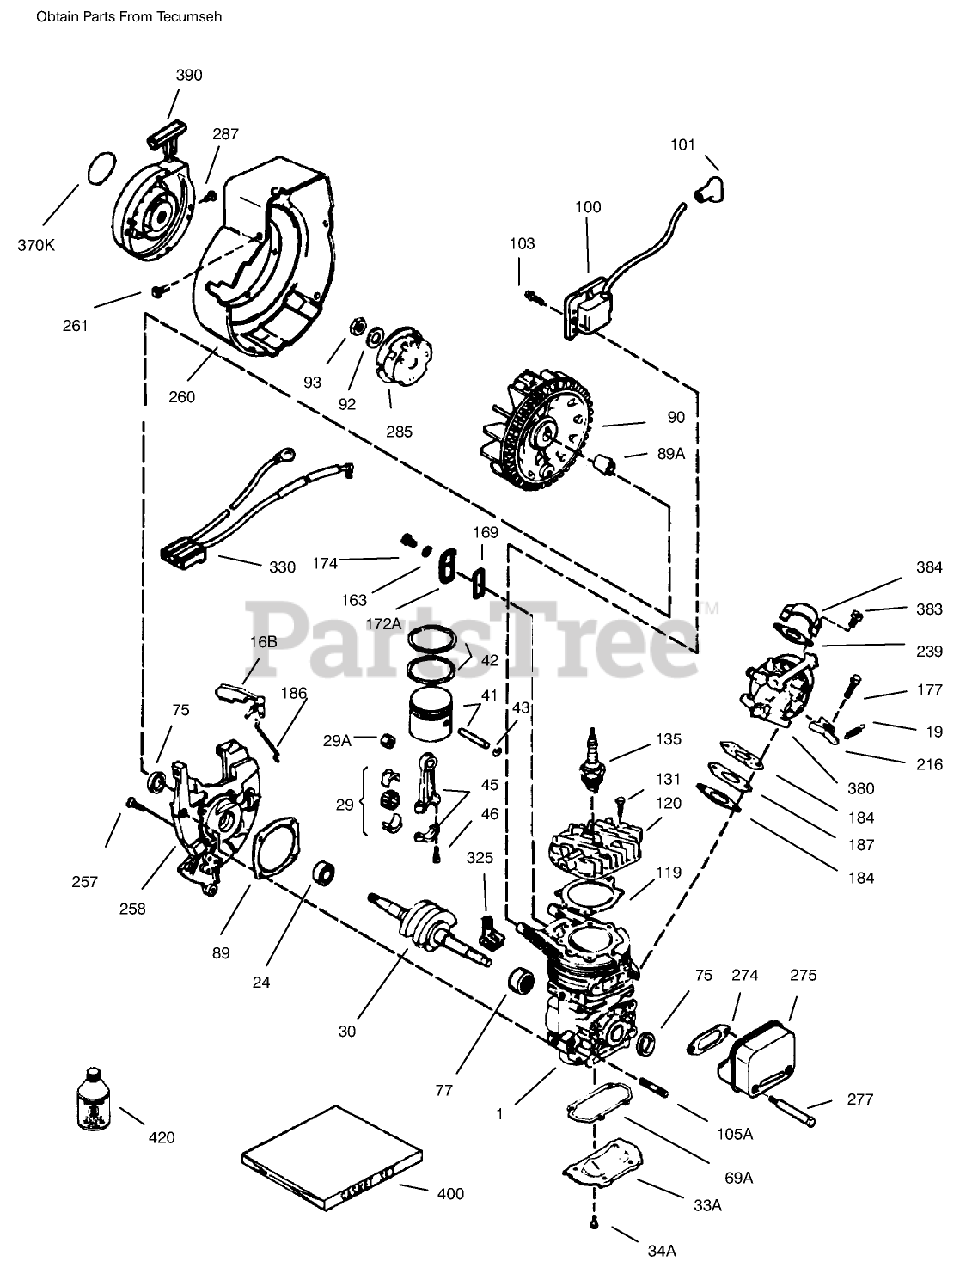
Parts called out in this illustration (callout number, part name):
1	Block Ass-y-Cylinder (Order short block if replacement is required)
3A4	Screw (T-25, 10-24 x 1/2)
16B	Vane-Air
19	Spring-Extention
24	Bearing-Ball
29	Needle Bearing and Liner Set (37 Needles)
29A	Bearing-Cartridge
30	Crankshaft
33A	Plate-Cover
41	Piston (Incl. Ref. #43)
42	Ring Set
43	Ring-Retaning
45	Rod Assy.-Connecting (Incl. Ref. #3, 3A 3B)
46	Bolt-Rod, Connecting
69	Gasket-Cover, Cylinder
69A	Gasket-Plate, Cover
75	Seal-Oil
77	Bearing-Cartridge
89A	Blade (20 inch)
90	CARB BODY S
92	Washer-Belleville
93	Nut-Flywheel
100	Solid State Ignition (Incl. 101)
101	Cover-Spark Plug
103	Screw (T-15, 10-24 x 15/16)
119	Gasket-Head, Cylinder
120	Head-Cylinder
131	Screw (T-30, 1/4-20 x 3/4)
135	Spark Plug-Resistor (R C J 8Y)
163	Washer
169	Cover-Compression, Release
172A	Cover-Release, Compression
174	Screw (T-25, 10-24 x 1/2)
177	Screw (5/32 Allen, 1/4-20 x 1)
184	Gasket-Carburetor
186	Governor-Link
187	Spacer
216	Lever-Adjusting, Rpm
239	2060A77 WIZARD ROTA
257	Screw (T-30, 1/4-20 x 5/8)
258	Base Ass-y-Blower Housing (Incl Ref. #20)
260	Housing-Blower
261	Screw (1/4-20 x 1/2)
274	Gasket-Exhaust
275	Muffler (Incl. Ref. #274 277)
277	Screw (1/4-20 x 2-3/4)
285	Cup-Starter
287	Screw (8-32 x 21/64)
325	Clip-Wire
330	Harness-Wire
370K	Decal-Tecumseh Logo for Top of Recoil Starter
380	Carburetor (Incl. ref. #184)
383	Baffle-Carburetor
384	Screw (T-25, 10-32 x 5/8)
390	Rewind Starter ASM
400	Gasket Set
422	2-Cycle Oil (8 oz.)
